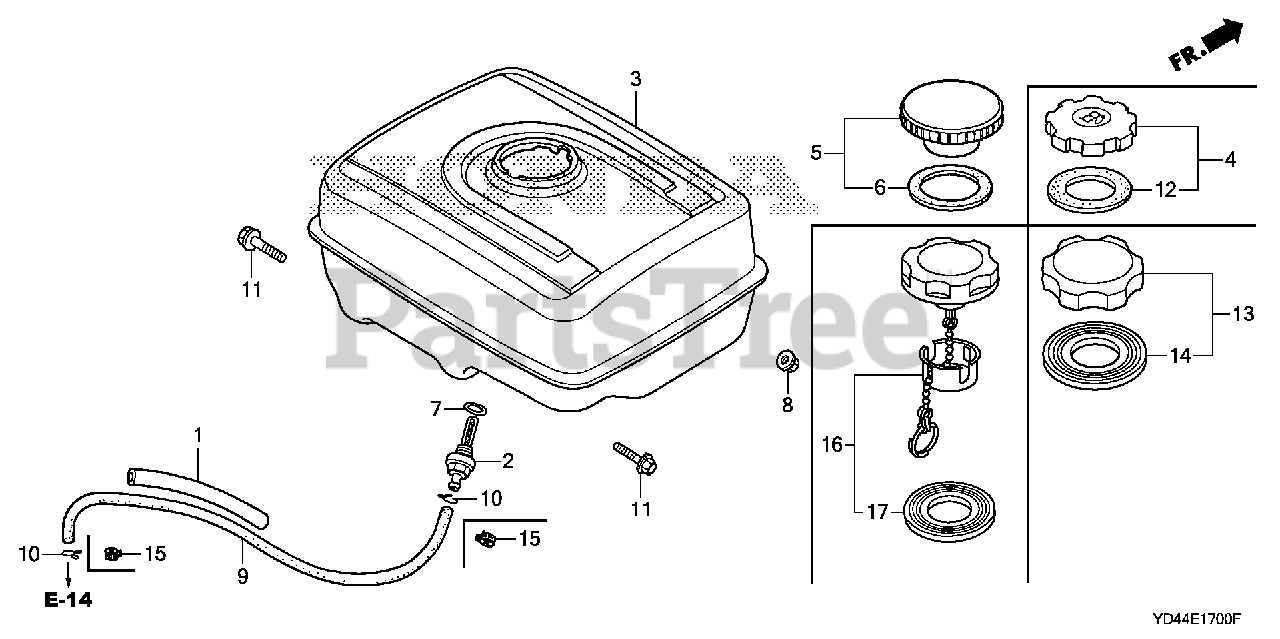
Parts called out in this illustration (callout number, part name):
1	RUBBER, SUPPORTER (107MM)
2	JOINT, FUEL TANK
3	TANK, FUEL *NH31* (MCKINLEY WHITE)
4	CAP, FUEL FILLER (BLACK) Use up to Engine SN 2115700.
4	CAP, FUEL FILLER (CHROME PLATED)
7	O-RING (14MM) (ARAI) Use up to Engine SN 2949254.
7	O-RING (14MM) (NOK)
8	NUT, FLANGE (8MM)
9	BULK HOSE, FUEL (4.5X3000) (Honda Code 5137104). (4.5X140)
9	TUBE, FUEL (4.5X235) (FKM)
10	CLIP, TUBE (B8)
11	BOLT, FLANGE (8X25)
12	GASKET, FUEL FILLER CAP Use from Engine SN 1543258.
13	CAP, FUEL FILLER (CHROME PLATED)
14	GASKET, FUEL FILLER CAP (39X62X3) (TOUYOUSYA)
15	CLIP, TUBE (D8)
16	CAP, FUEL FILLER
17	GASKET, FUEL FILLER CAP
